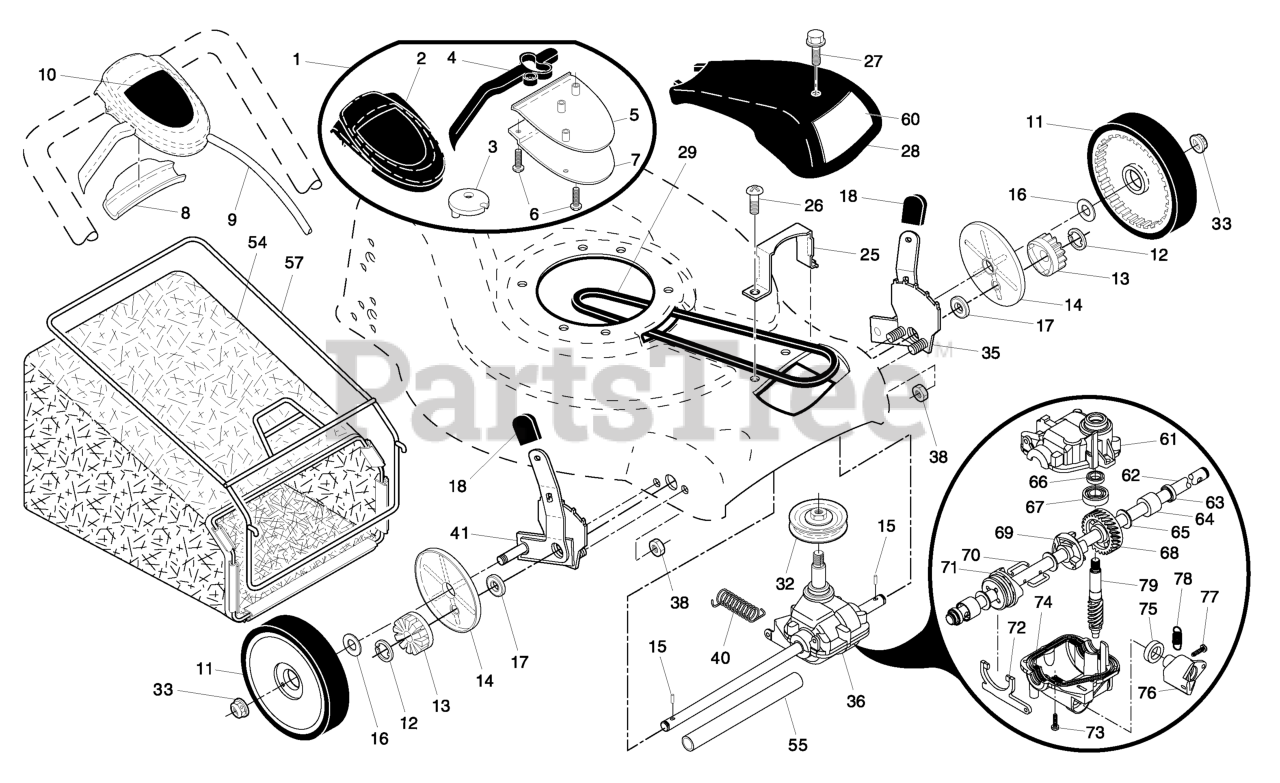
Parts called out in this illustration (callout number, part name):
1	CONTROL.DR.EZ.FWGD.SHORT.GY/BL
2	COVER TOP AUTO WALK CONTROL
3	PULLEY.CAM.DRIVE.CONTROL.HV
4	LEVER, AUTOWALK DRIVE CONTROL
5	COVER BOTTOM AUTO WLK CONTROL
6	SCREW, PHILLIPS HEAD 10 X 5/8
7	BRACKET.DRIVE.CONTROL.MOUNT.BL
8	EZ WALK SNAP COVER PLATE
9	CONTROL.DR.EZ.FWGD.SHORT.GY/BL
10	DECAL, DRIVE
11	WHEEL.8X1.75.H3SPK.RAD3.GY.BU3
12	E-RING 7/16 RE
13	PINION.14.TEETH.FGD
14	COVER.DUST.WHEEL
15	PAWL.DRIVE
16	WASHER FLUT
17	BEARING
18	SELECTOR KNOB
25	KEEPER.BELT.21.EZ.FWGD
26	SELF-TAPPING SCREW 5/16-18X3/4
27	SCREW, HEX HD TAPPING #10-24 1
28	COVER.DRIVE.21.FWGD.GRAY
29	BELT.DRIVE.FGD.
32	RP PULLEY.DRIVE.EZ
33	HEX FLANGE LOCKNT
35	KIT WHEEL ADJUSTER LH
36	TRANSMISSION.21RD
38	LOCKNUT.NYLOC.1/4-20
40	SPRING RETURN
41	KIT WHEEL ADJUSTER RH
54	GBAG.34710247.SILVER.H
55	DRIVESHAFT COVER
57	FRAME, GRASSBAG
60	DECAL DRIVE COVER
61	GEARCASE.HOUSING
62	SHAFT.OUTPUT
63	SEAL.OUTPUT.SHAFT
66	SEAL INPUT SHAFT
68	GEAR.27.TEETH.WALK.MOWER
70	WIRE, FORMED (15966)
74	GEARCASE.HOUSING.LOWER
77	SCREW.LEVER.
79	SHAFT INPUT (13041)
